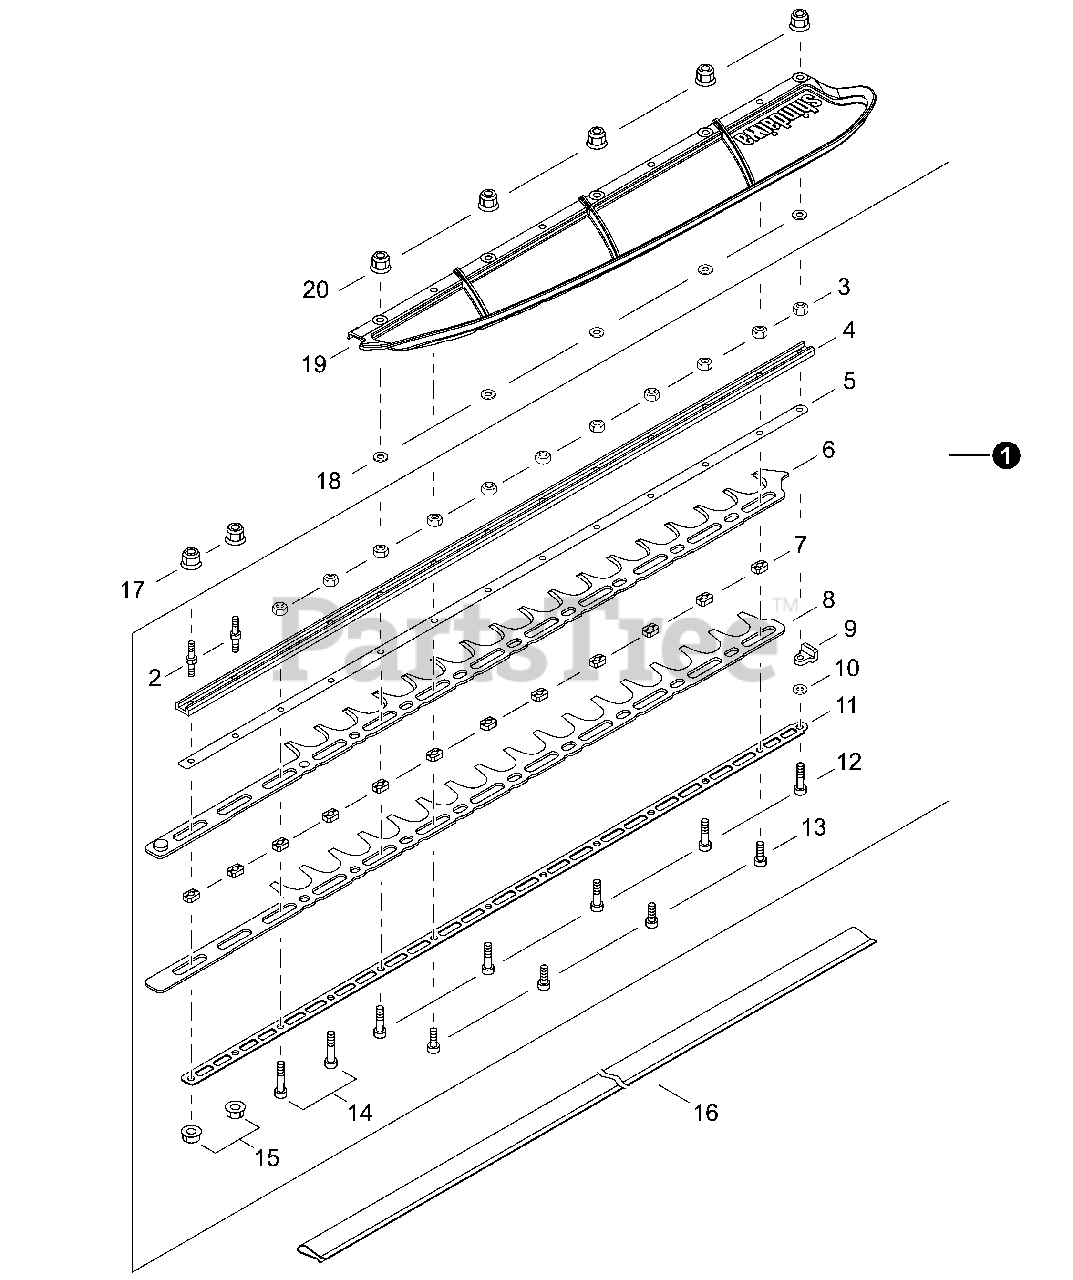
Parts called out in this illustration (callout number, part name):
1	CUTTER ASSY, 40"
2	STUD, MOUNTING M5
4	SUPPORT, CUTTER 40"
5	SUPPORT, CUTTER 40"
6	CUTTER 40"
8	CUTTER 40"
11	SUPPORT, CUTTER 40"
12	BOLT, TORX 5×25
13	BOLT, TORX 5×16
14	BOLT, TORX 5×30
16	SCABBARD
18	WASHER, FLAT 5.5×10×0.8
19	DEFLECTOR, DEBRIS
